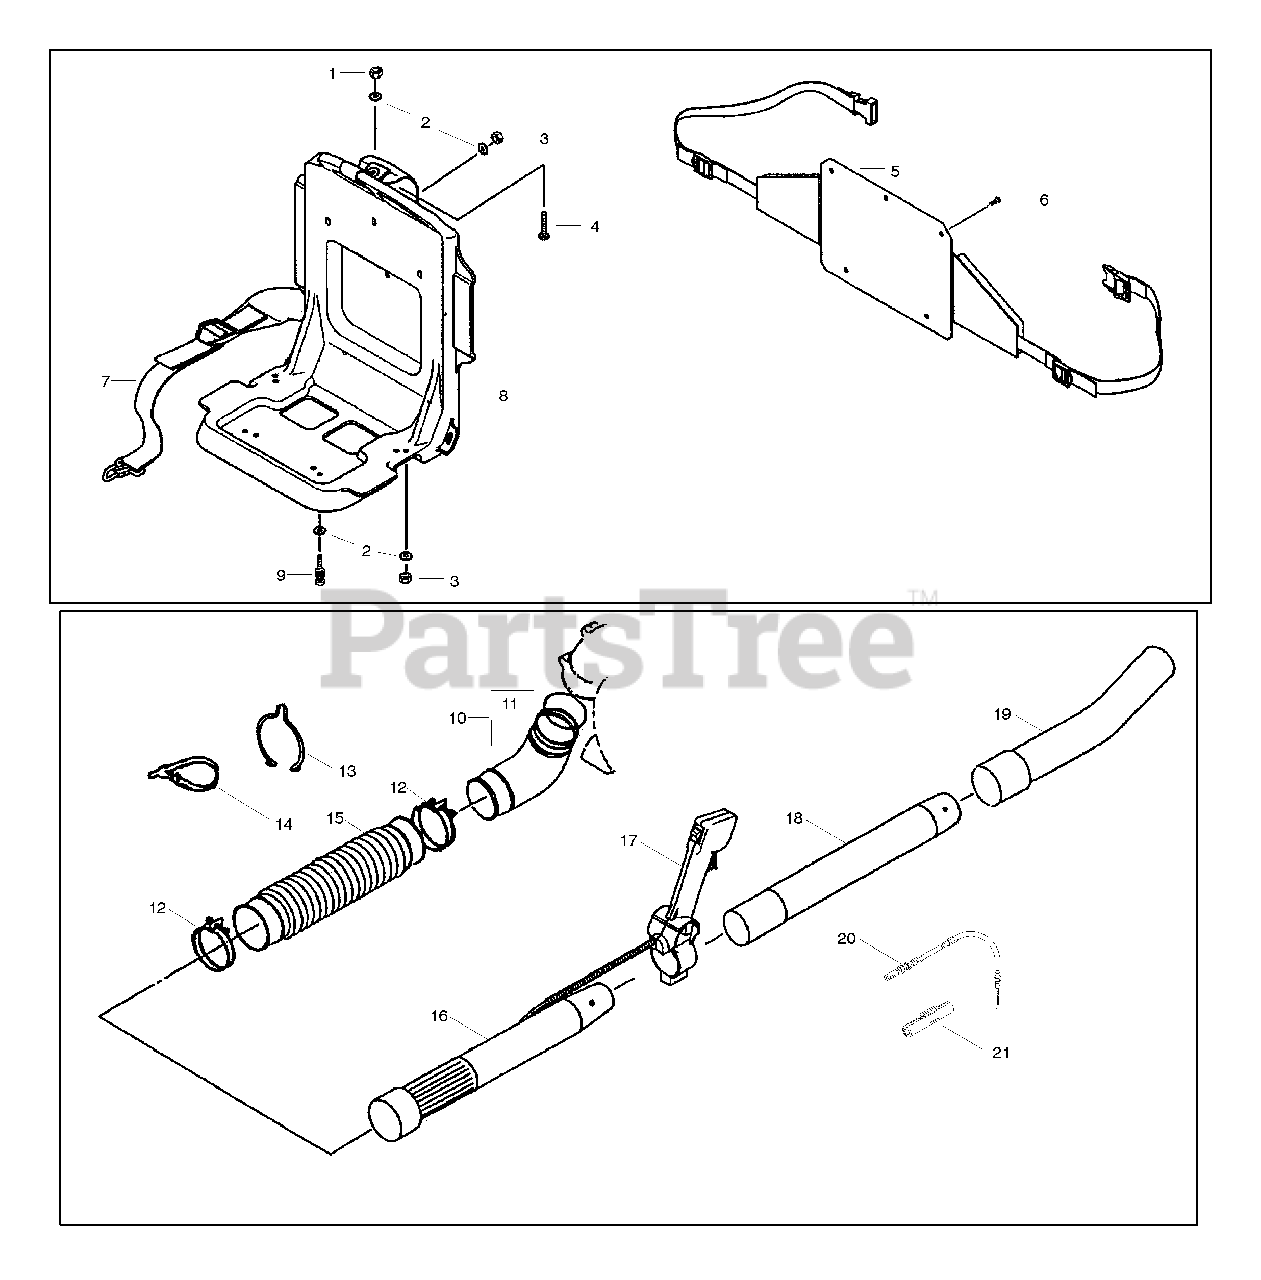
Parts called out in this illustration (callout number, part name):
1	Nut-Nylon Flange
3	Nut-Hex-U
4	Screw-Truss
5	Pad-Knapsack
7	Band-Shoulder
8	Frame-Knapsack
9	Screw m6x15
10	Pipe-Elbow C.P.
11	O-Ring
12	Band-Hose
13	Clamp-Wire
14	Band-Wire
15	Pipe-Flex
16	Pipe-Base
17	Assy-Throttle Lever
18	Pipe-Middle
19	Pipe-Bend
20	Cable-Throttle
